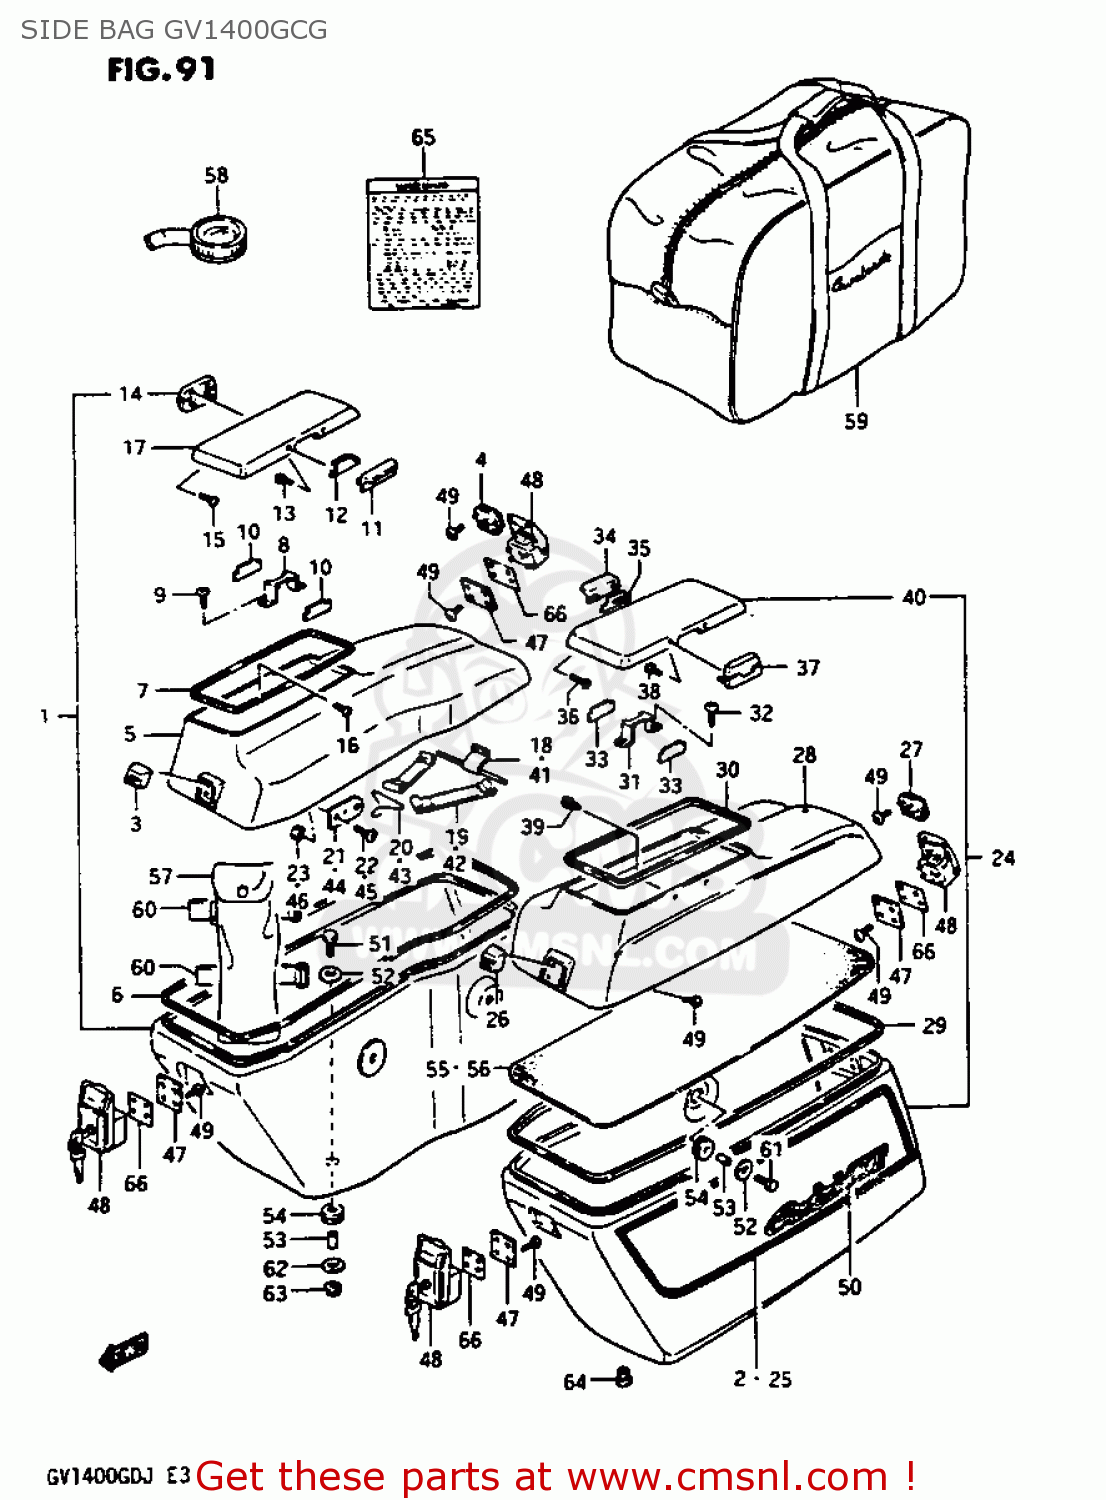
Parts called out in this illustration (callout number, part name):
1	SIDE BAG ASSEMBLY,RIGHT
2	TAPE SET,SIDE BAG,RIGHT
3	PLATE,TRUNK LID LOCK
4	PLATE,SIDE BAG LID LOCK
5	LID,SIDE BAG,RIGHT
6	SEAL,SIDE BAG
7	SEAL,SIDE BAG
8	HOLDER,LID LOCK MAGNET
9	SCREW
10	PLATE,LID LOCK
11	LEVER,SIDE POCKET OPEN
12	PLATE,LID LOCK NO.1
13	SCREW
14	HINGE,LID SIDE BAG POCKET
15	SCREW
16	SCREW
17	LID,SIDE BAG POCKET
18	PLATE,LUGGAGE BAND LID
19	BAND,LUGGAGE LID
20	.HOOK
21	PLATE, FRONT
22	SCREW, FRONT & REAR
23	NUT 5MM
24	SIDE BAG ASSEMBLY,LEFT
25	TAPE SET
26	PLATE,TRUNK LID LOCK
27	PLATE,SIDE BAG LID LOCK
28	LID,SIDE BAG,LEFT
29	SEAL,SIDE BAG
30	SEAL,SIDE BAG
31	HOLDER,LID LOCK MAGNET
32	SCREW
33	PLATE,LID LOCK
34	LEVER,SIDE POCKET OPEN
35	PLATE,LID LOCK NO.1
36	SCREW
37	HINGE,LID SIDE BAG POCKET
38	SCREW
39	SCREW
40	LID,SIDE BAG POCKET
41	PLATE,LUGGAGE BAND LID
42	BAND,LUGGAGE LID
43	.HOOK
44	PLATE, FRONT
45	SCREW, FRONT & REAR
46	NUT 5MM
47	SET PLATE,LOCK SIDE BA
48	LOCK SET,SIDE BAG
49	SCREW
50	EMBLEM
51	BOLT
52	WASHER (6.5X29X1.6)
53	SPACER(6.3X9.3X16.5)
54	CUSHION
55	SEAT, BOTTOM RH
56	SEAT, BOTTOM LH
57	TOOL ASSY
58	GAUGE ASSY,AIR PRESSURE
59	LUGGAGE BAG,SIDE BAG
60	BAND
61	BOLT
62	WASHER (6.5X18X2)
63	NUT
64	CAP(OD:12)
65	LABEL (WARNING TRAVEL T
66	PACKING SEAT
